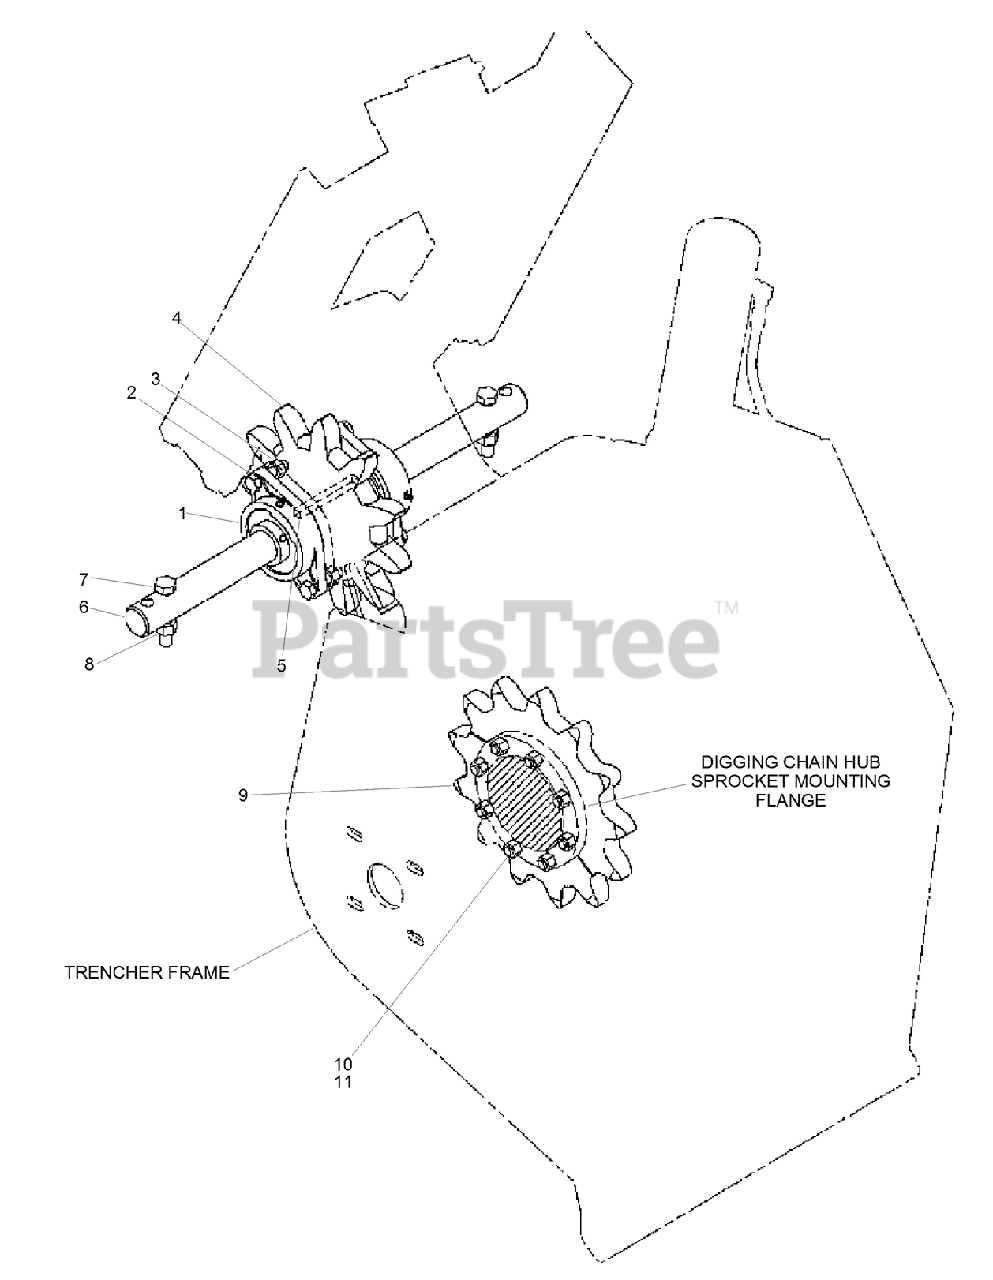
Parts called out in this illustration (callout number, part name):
1	BEARING-BALL, 2-BOLT FLANGE (2 IN)
2	BOLT - 5/8 x 2-1/2
3	NUT-LOCK, HEX
4	SPROCKET - Auger Drive, 408 Chain
5	KEY-SQUARE
6	SHAFT-AUGER
8	NUT-Prev Trq 3/4 GRC CAD Direct
9	SPROCKET - Split, 408 Chain
10	BOLT - 9/16 x 3
11	NUT-HEX
